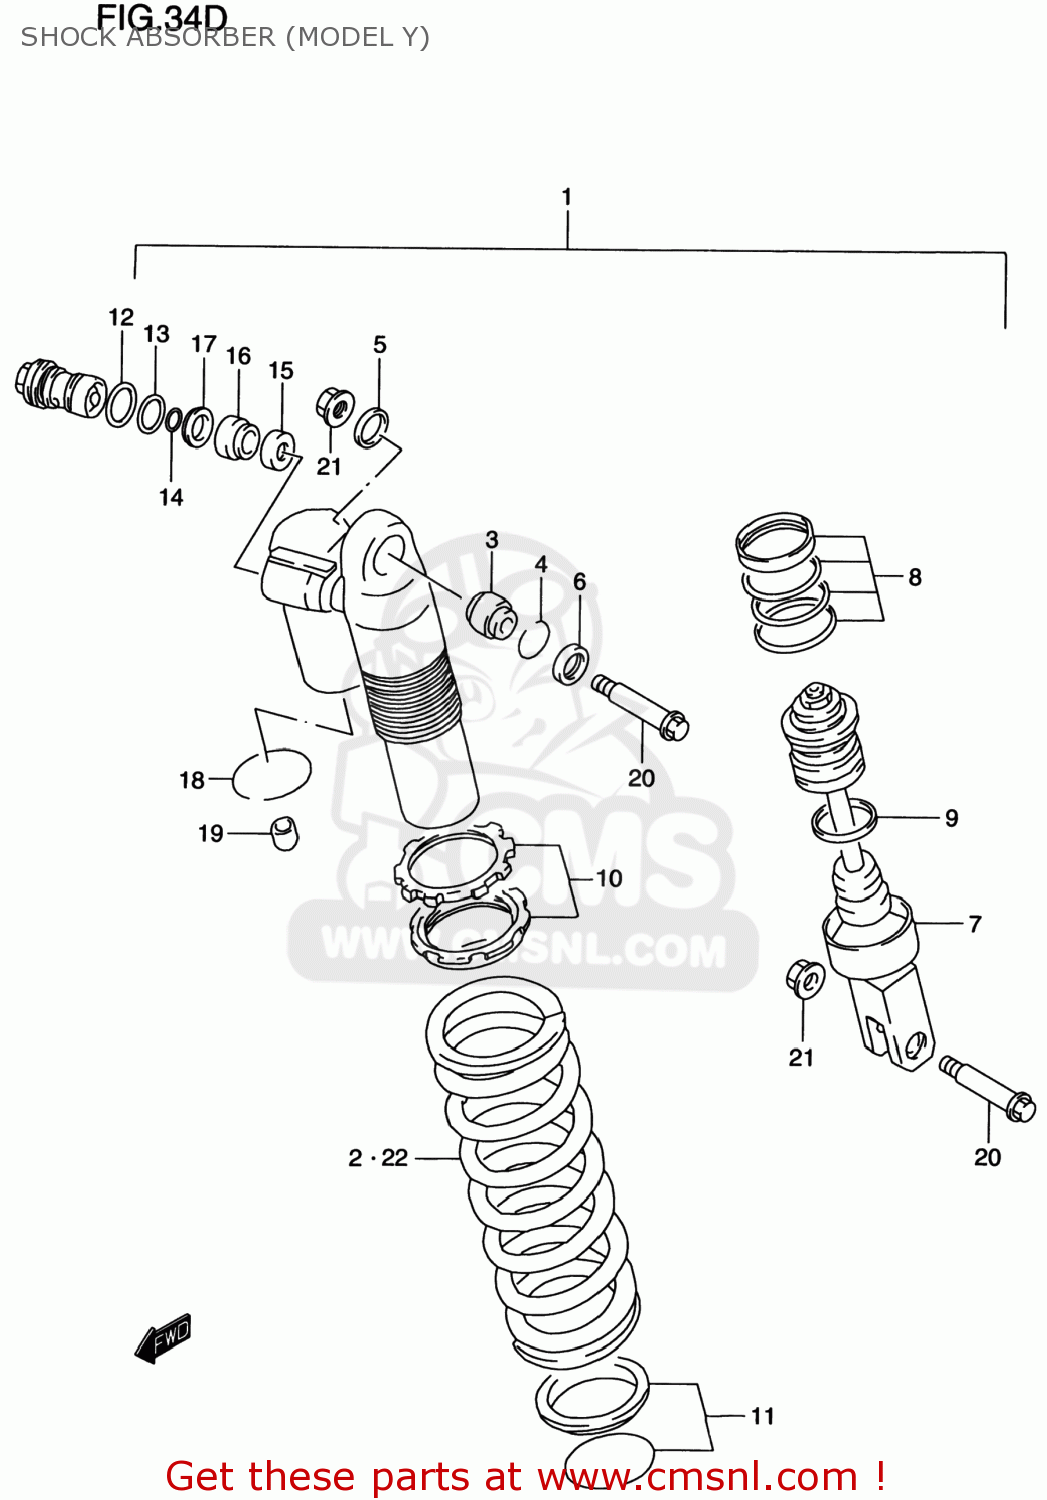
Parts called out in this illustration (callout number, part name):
1	ABSORBER ASSY,RR SHOCK
2	SPRING,RR(K=5.0X5.4)
3	BEARING,RR SHOCK ABSORBER
4	RING,STOPPER
5	SEAL,DUST UPR,R
6	SEAL,DUST UPR,L
7	ROD,PISTON
8	O RING SET
9	RING,STOPPER
10	ADJUSTER SET
11	SPRING SEAT SET
12	O RING
13	O RING
14	O-RING
15	COLLAR,ORIFICE
16	PIECE,BOTTOM
17	SEAT,VALVE
18	RING,STOPPER
19	CAP
20	BOLT(10X47.5)
21	NUT
22	SPRING,RR(K=5.2)
